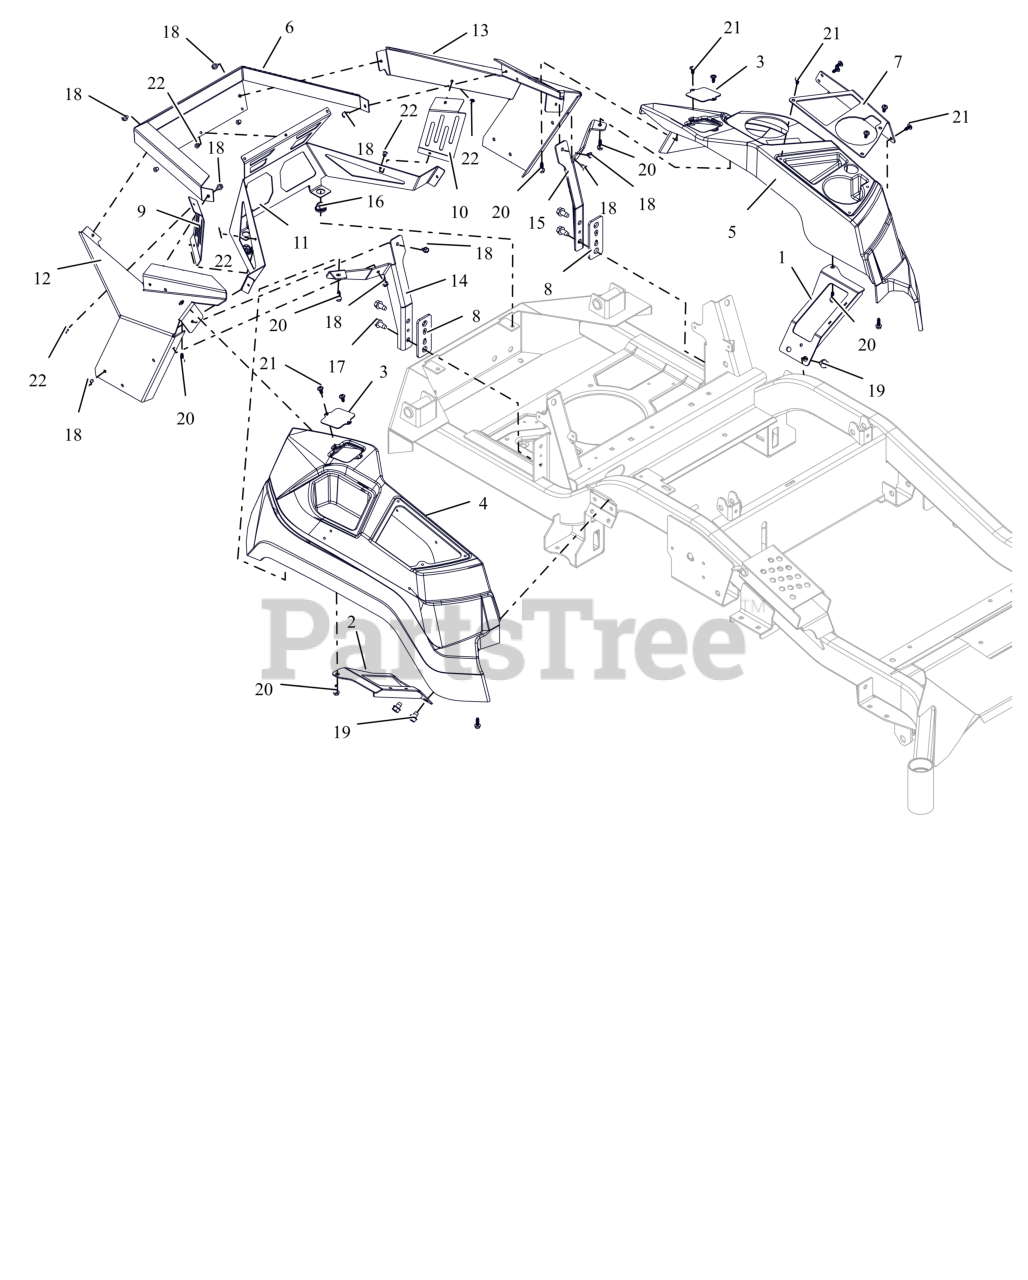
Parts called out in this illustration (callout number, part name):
1	WLDMT, LH FENDER MOUNT
2	WLDMT, RH FENDER MOUNT
3	PLATE, ROPS HOLE-HD
4	FENDER, RH APEX - 2017
5	FENDER, LH APEX
6	GUARD,ENGINE WRAP
7	PLATE, APEX CUP HOLDER COVER
8	PLATE, CONTROL PANEL SPACER
9	SHIELD,RH ENGINE GUARD VALVE
10	SHIELD,LH ENGINE GUARD VALVE
11	GUARD, ENGINE
12	PANEL, RH REAR FENDER MOUNT
13	PANEL, LH REAR FENDER MOUNT
14	BRKT, RH FENDER MTG (ORANGE)
15	BRKT, LH FENDER MOUNT (ORANGE)
16	GROMMET, 10MM BOLLHOFF
17	SCR,TAP .375-16X.75 HWH TR ZCC
18	SCR,TAP .25-20X.375 HWH TR ZCC
19	SCR,TAP .375-16X.50 HWH TR ZCC
20	SCR, PLASTITE .25-10X.75 ZCC
21	SCR-PAN .25-15X.50 6L H/LZB500
22	RIVET, .1875 AL/AL .126-.250
